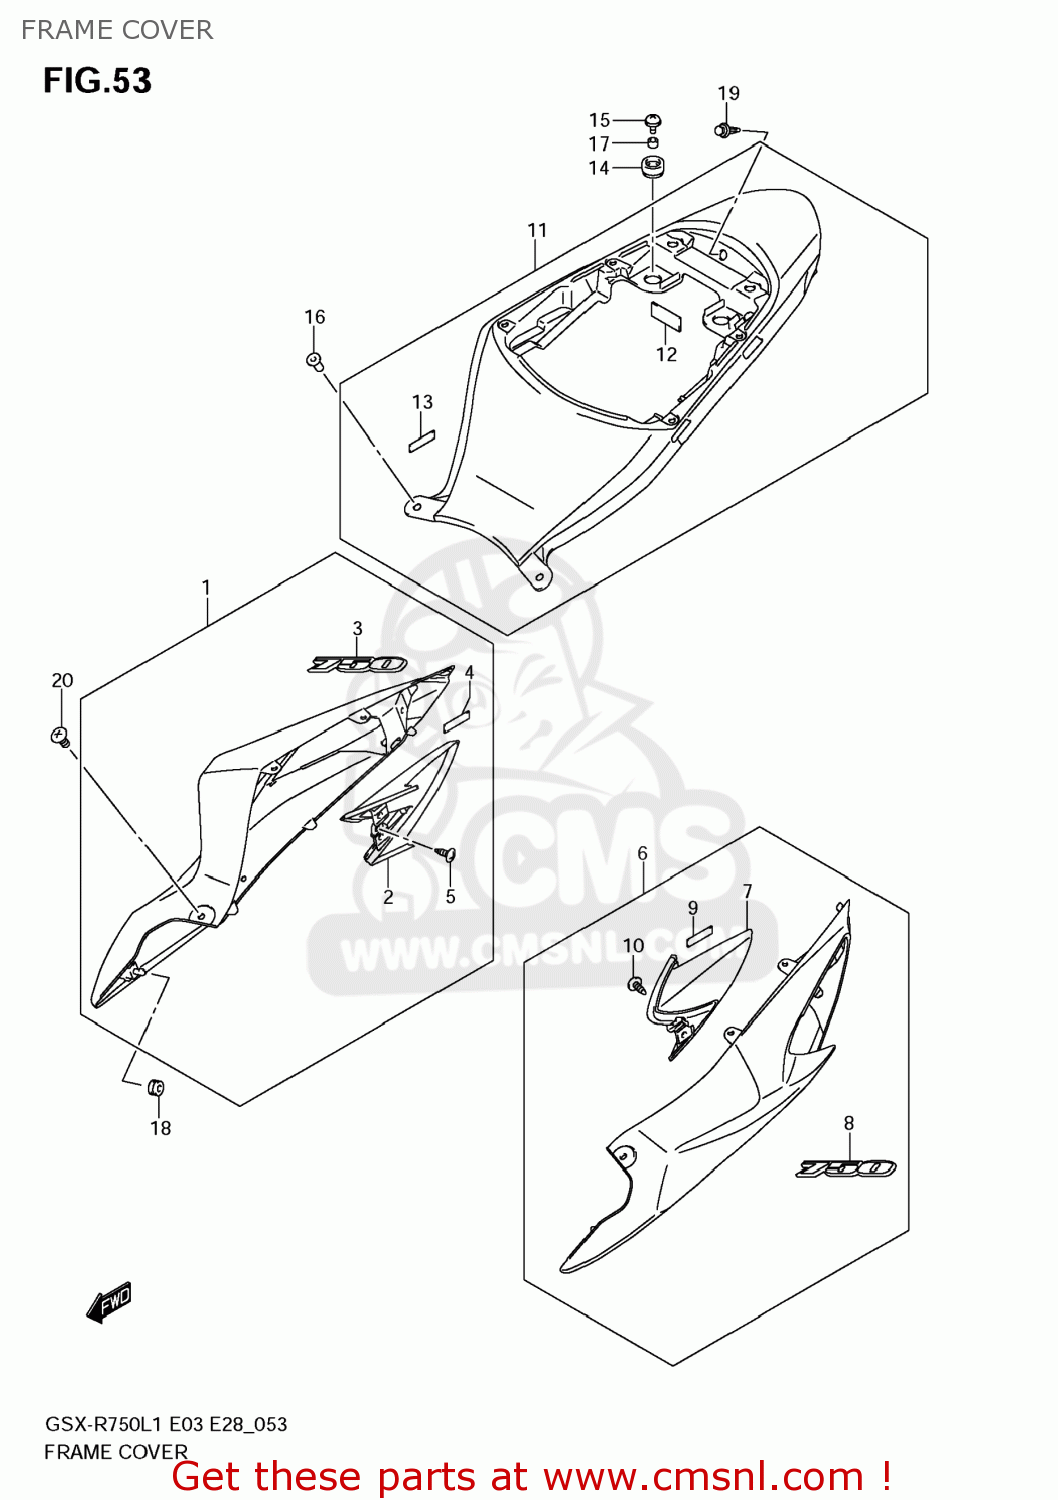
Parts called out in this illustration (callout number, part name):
1	COVER ASSY,FRAME,R(WHITE)
2	COVER,FRAME RR,R
3	EMBLEM,750
4	TAPE(6X25X0.13)
5	SCREW
6	COVER ASSY,FRAME,L(WHITE)
7	COVER,FRAME RR,L
8	EMBLEM,750
9	TAPE(6X25X0.13)
10	SCREW
11	COVER ASSY,FRAME CTR
12	CUSHION
13	TAPE(6X25X0.13)
14	CUSHION,FRAME COVER RR
15	SCREW(6X16)
16	NUT
17	SPACER(6.5X10X7)
18	CUSHION
19	CLIP(BLACK)
20	SCREW
